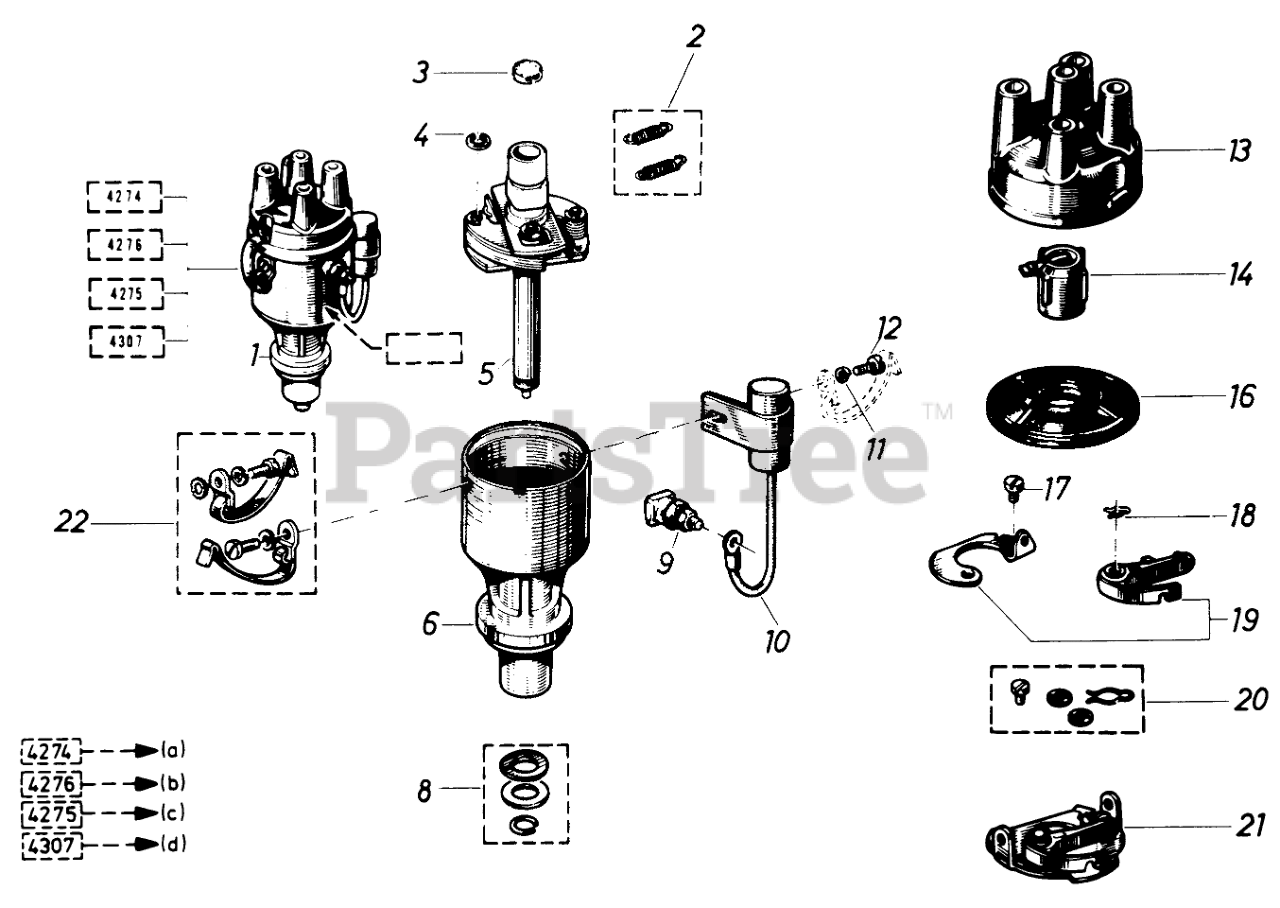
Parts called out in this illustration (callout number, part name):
1	Distributor
2	Spring Set
3	Lubricating Felt
4	Retaining Ring
5	Axle Cam Shaft and Wts.
6	Housing
8	Set of Lock Washers
9	Joining Screw
10	Condenser
11	Lock Washer
12	Screw
13	DISTRIBUTOR CAP
14	DISTRIB CAM ROTOR
16	Protection Disc
17	Screw
18	Spring Clamp
19	CONTACT LEVER POINT
20	Set of Fastening Parts
21	Point Set W/Plate
22	Retaining Spring Assy.
